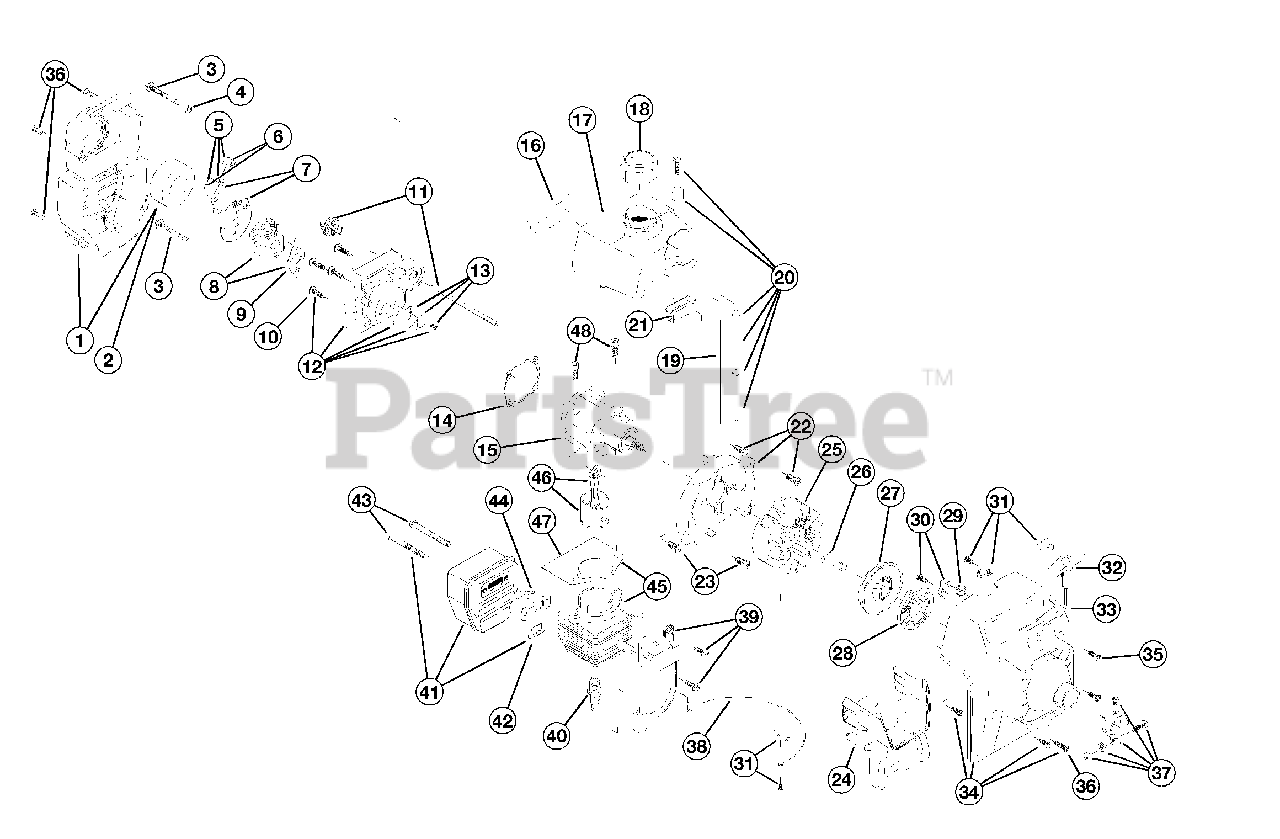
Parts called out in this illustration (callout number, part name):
1	Air Cleaner/Muffler Cover Assembly
2	Air Cleaner Filter
3	Carburetor Mounting Screws
4	Wavey Washer
5	Choke Lever Assembly
6	Choke Knob & Screw
7	Choke Lever & Plate
8	Carburetor Assembly
9	Carburetor Gasket
10	Carb Mount Screw
11	Primer and Hose Assembly
12	Carburetor Mount Assembly
13	Reed Assembly
14	Carburetor Mount Gasket
15	Crankcase Service Assembly
16	Rear Mounting Pad
17	Fuel Tank Assembly
18	Fuel Cap Assembly
19	Fuel Return Line
20	Fuel Line Assembly
21	Front Mounting Pad
22	Shroud Assembly
23	Shroud Screw
24	Shroud Extension and Stand
25	Flywheel Assembly
26	Square Nut Drive
27	Recoil Pulley
28	Recoil Spring
29	Rope Guide
30	Pulley Retainer Assembly
31	Switch Assembly
32	Pull Handle
34	Starter Housing Assembly
35	Housing Screw
36	Cover Screw
37	Upper Clamp Assembly
38	Wire Lead
39	Module Assembly
40	Spark Plug
41	Muffler Assembly
42	Exhaust Gasket
43	Muffler Mounting Bolt Assembly
44	Spark Arrestor
45	Cylinder Assembly
46	Piston and Rod Assembly
47	Cylinder Gasket
48	Cylinder Bolt
